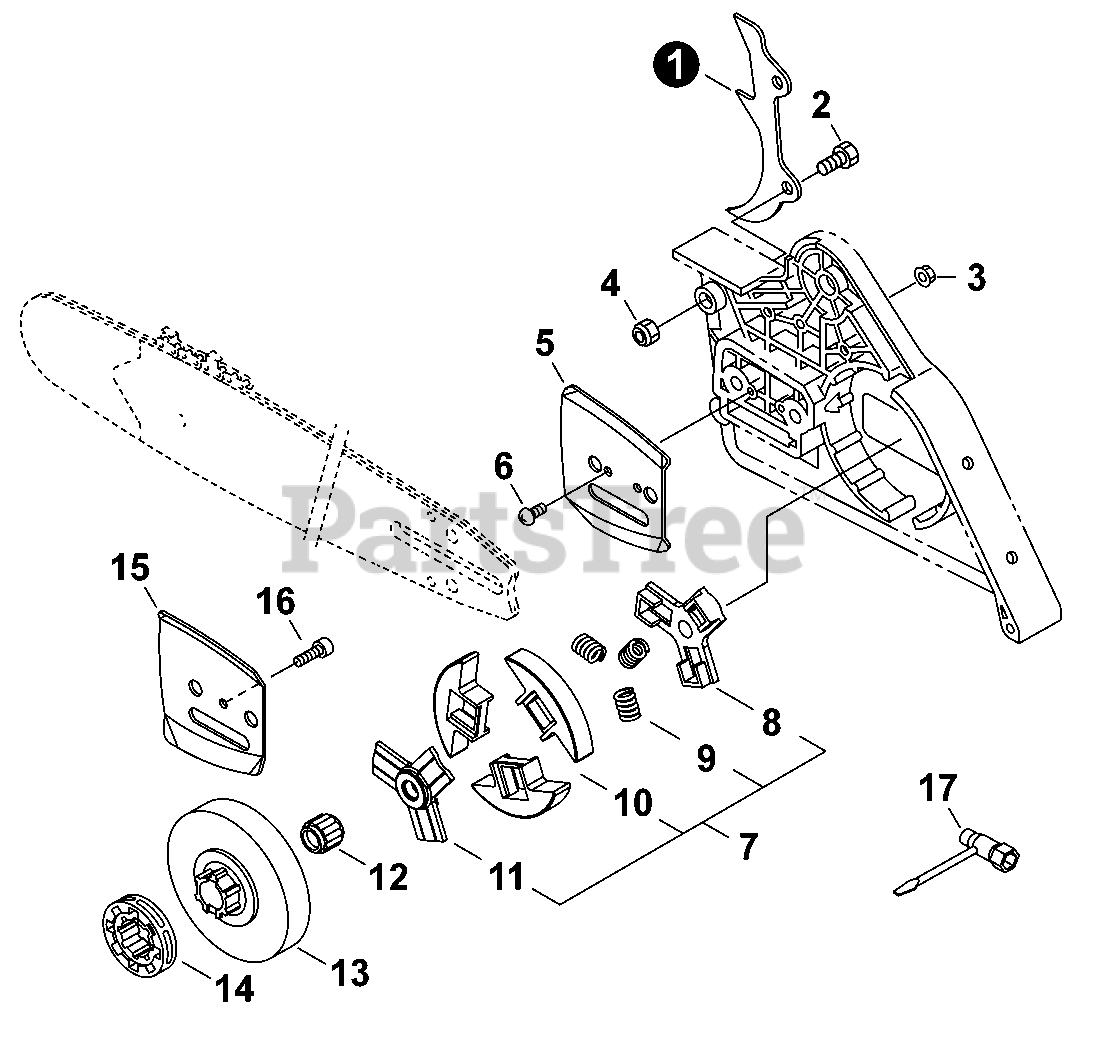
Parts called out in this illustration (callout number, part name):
1	SPIKE, BUMPER
3	NUT, FLANGE M8×1.25
4	NUT, LOCK 6
5	PLATE, GUIDE - OUTER
6	SCREW 3×6
7	CLUTCH ASSY
8	HUB, CLUTCH
9	SPRING, CLUTCH
10	SHOE, CLUTCH
11	HUB, CLUTCH
12	BEARING, NEEDLE
13	DRUM, CLUTCH
14	SPROCKET, RIM 3/8"×7T
15	PLATE, GUIDE - INNER
16	SCREW 4×8
17	T-WRENCH 13×19 L= 180
